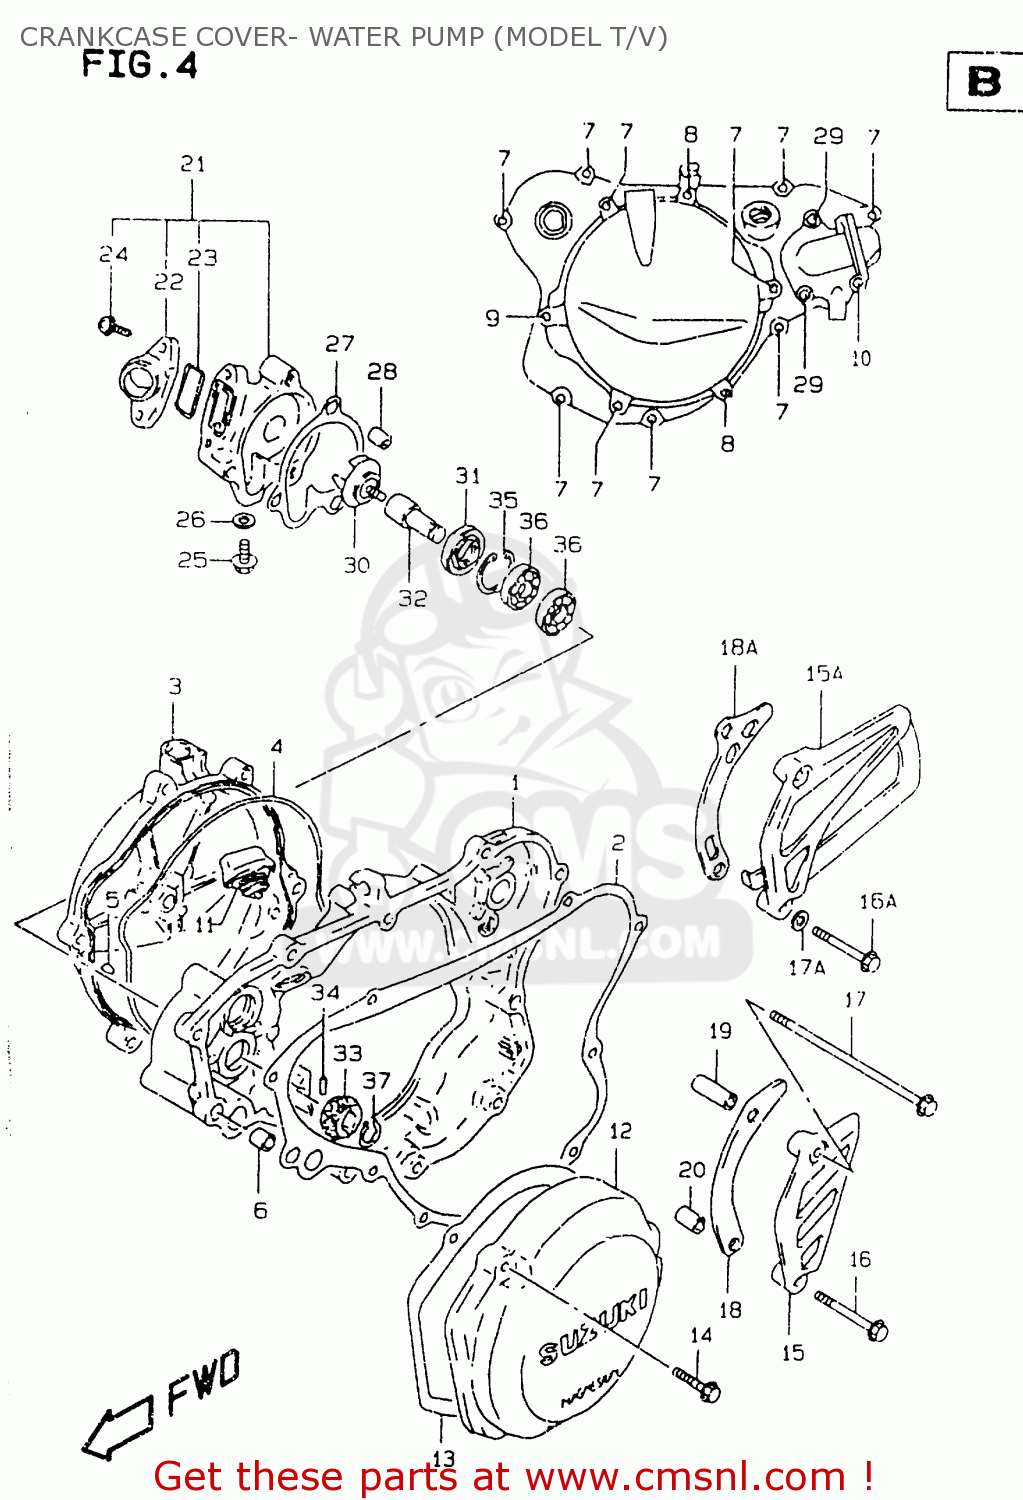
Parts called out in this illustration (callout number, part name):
1	COVER SET,CLUTCH
2	GASKET,CLUTCH COVER (NAS)
3	COVER,CLUTCH OUTER
4	O RING,CLUTCH COVER OUTER
5	PIN
6	PIN
7	SCREW
8	BOLT
9	BOLT
10	BOLT(6X100)
11	PLUG SET
12	COVER,MAGNETO
13	GASKET,MAGNETO COVER (NAS)
14	SCREW
15	COVER,ENGINE SPROCKET
15A	COVER,ENGINE SPROCKET
16	BOLT
16A	BOLT,G/S SWITC
17	BOLT(6X100)
17A	WASHER (6.2X14X2)
18	PLATE,FR CHAIN GUIDE
18A	PLATE,FR CHAIN GUIDE
19	SPACER(6.5X10.5X25)
20	SPACER(6.5X10.5X12)
21	CASE ASSY,WATER PUMP
22	CONNECTOR
23	O RING,WATER PUMP CONNECTOR
24	SCREW 6X16
25	BOLT
26	WASHER
27	GASKET,WATER PUMP CASE (NAS)
28	PIN
29	BOLT
30	IMPELLER,WATER PUMP
31	SEAL,WATER PUMP OIL
32	SHAFT,WATER PUMP
33	GEAR,WATER PUMP DRIVEN(NT:22)
34	PIN(3X13.8)
35	CIRCLIP
36	BEARING
37	CIRCLIP,10MM
